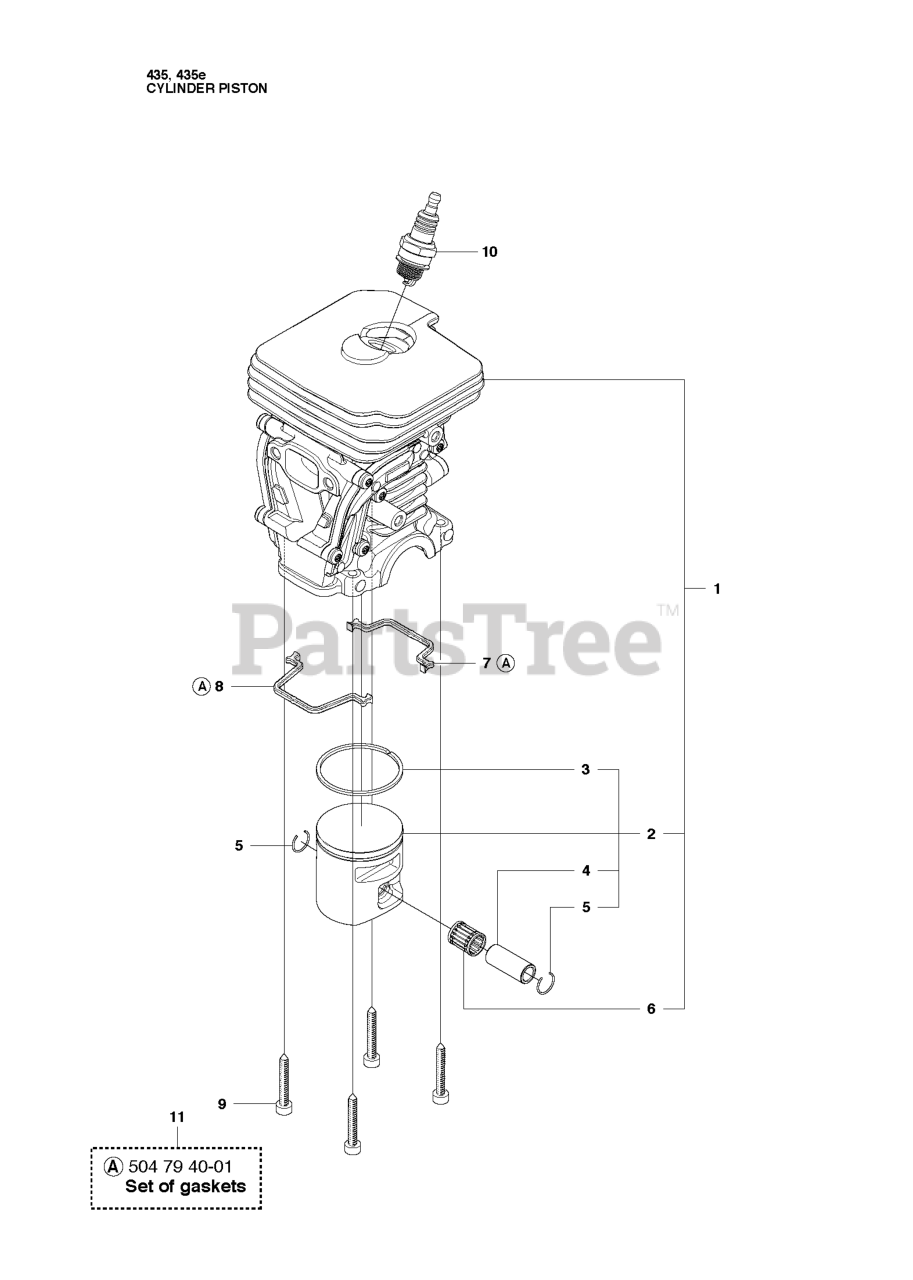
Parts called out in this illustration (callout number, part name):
1	ASSY, CYLINDER 435 AND 435E
2	PISTON ASSY
3	PISTON RING
4	PISTON PIN
5	LOCKING RING
6	SUPPORT BUSHING
9	SCREW MC6S 5X25
10	SPARK PLUG M14X1.25 NGK BPMR7A
11	GASKET SET
